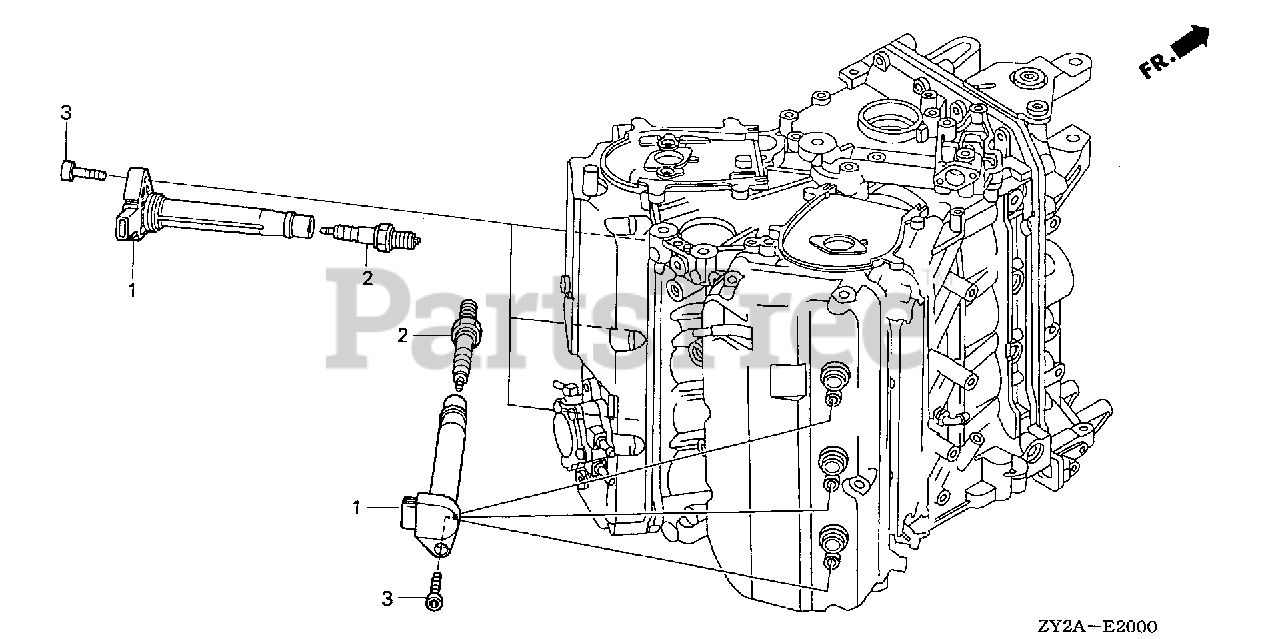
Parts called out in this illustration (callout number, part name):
1	COIL, PLUG HOLE
2	SPARK PLUG (IZFR6F11) (NGK)
2	SPARK PLUG (VKJ20RZ-M11) (DENSO)
3	BOLT, SOCKET (6X25)
